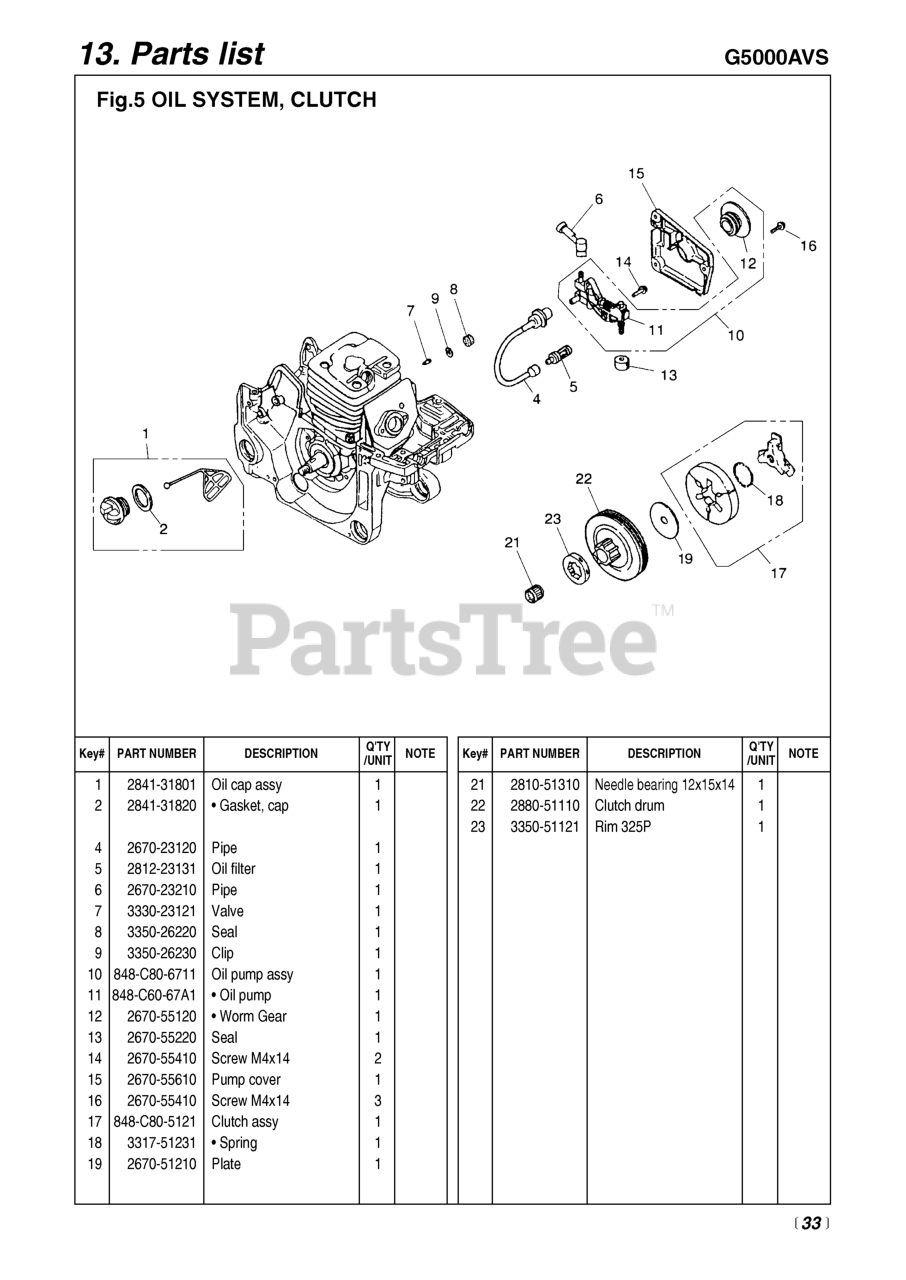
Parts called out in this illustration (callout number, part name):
1	CAP ASSY.
2	GASKET
4	PIPE, OIL
6	PIPE, OIL OUTLET
7	VALVE (RPLS -23120)
8	SEAL, BREATHER
9	CLIP
10	OIL PUMP ASSY.(RPLS.2880-55100
11	OIL PUMP (RPLS 2850-55110)
12	GEAR
13	SEAL
14	SCREW
15	COVER, PUMP
16	SCREW
17	CLUTCH ASSEMBLY
18	SPRING
19	PLATE, THRUST
21	BEARING (RPLS 2670-51310)
22	DRUM, CLUTCH (RPLS 2670- )
23	RIM SPROCKET, .325, 7-TOOTH
